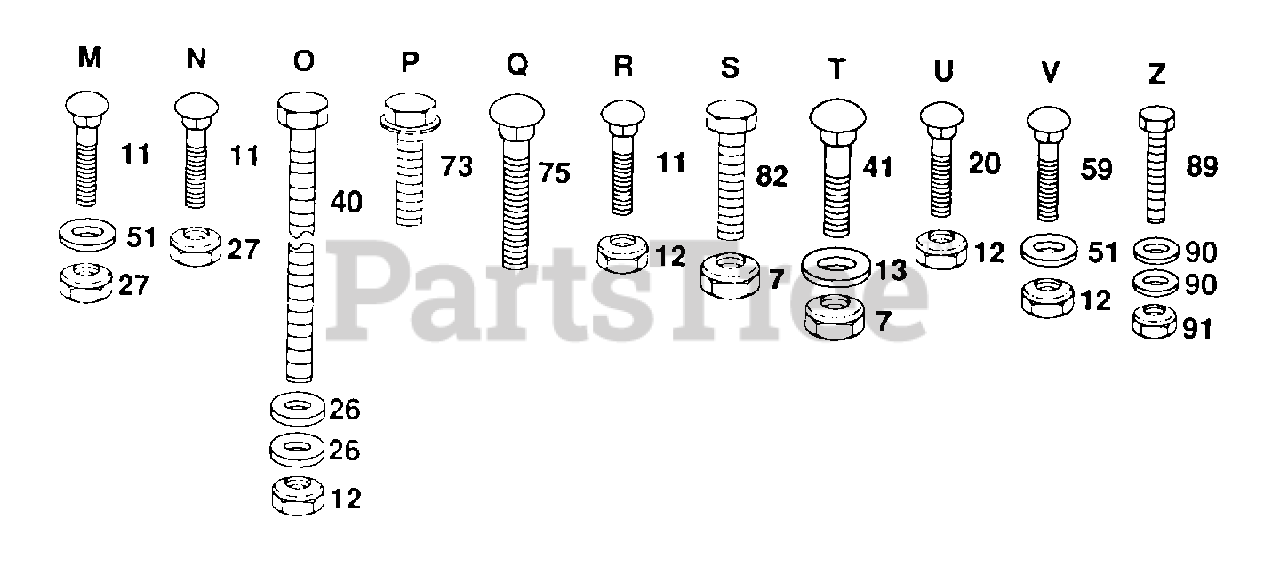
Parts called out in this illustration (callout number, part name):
11	BOLT
13	WASHER
20	BOLT
26	WASHER M
40	BOLT - HEX 3/8 - 16 X 3
51	WASHER
73	SCREW
75	BOLT
82	BOLT
89	BOLT LT
90	WASHER
